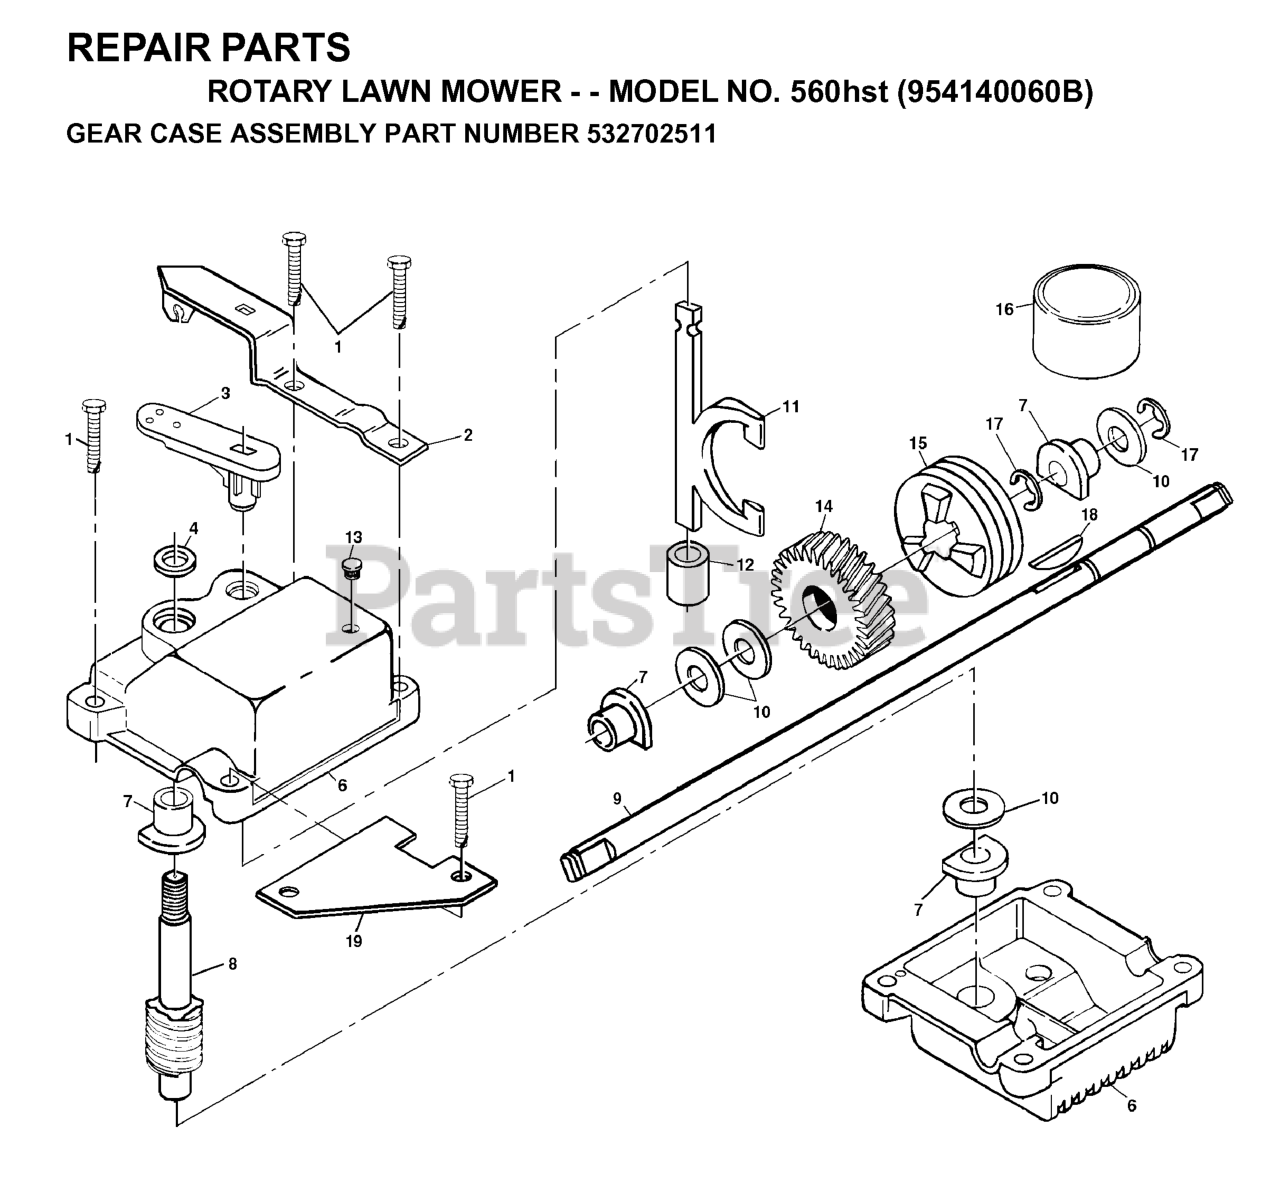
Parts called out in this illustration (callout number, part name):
1	SCREW
2	BRACKET
5	GROOVED PIN
8	WORM SHAFT
9	DRIVE SHAFT, 20-5/8"
10	THRUST WASHER
11	YOKE.VIBRATORY FINISH.
13	PLUG.AUGER.GEAR.BOX.SNOW
14	GEAR.HELICAL
15	CLUTCH JAW
16	GREASE
18	HI PRO KEY
19	BRACKET SPRING
